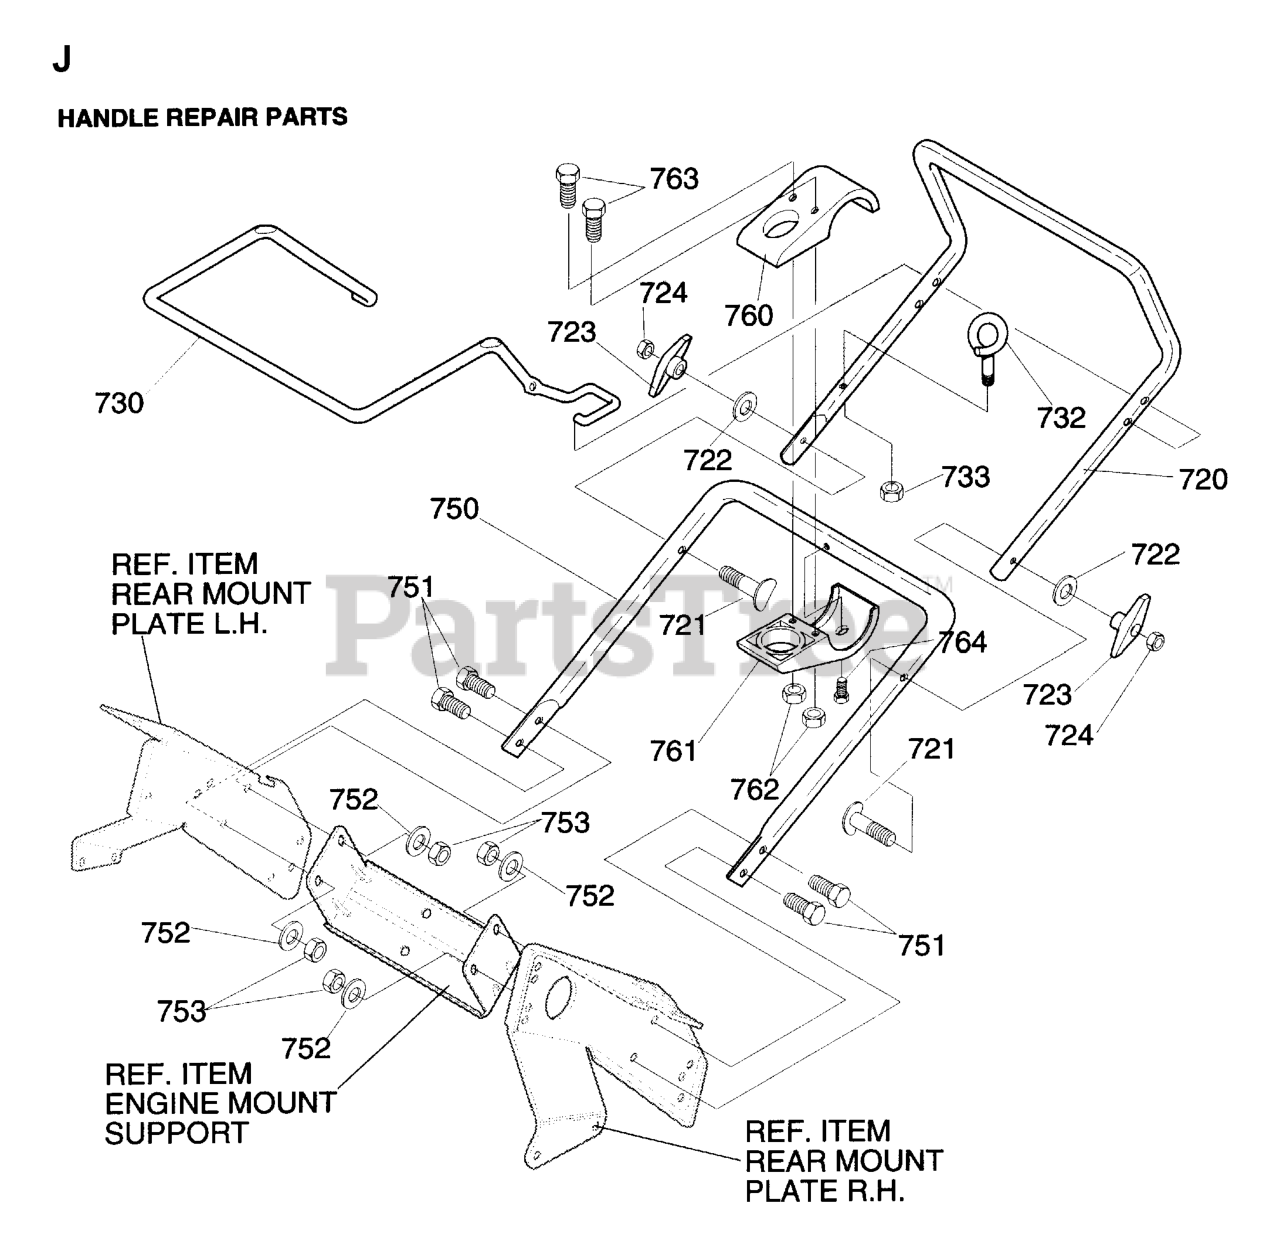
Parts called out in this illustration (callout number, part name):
724	NUT
733	LOCKNUT
751	BOLT.FIN.HEX.5/16-18X3/4
752	WASHER - 15X7.3X1.6
